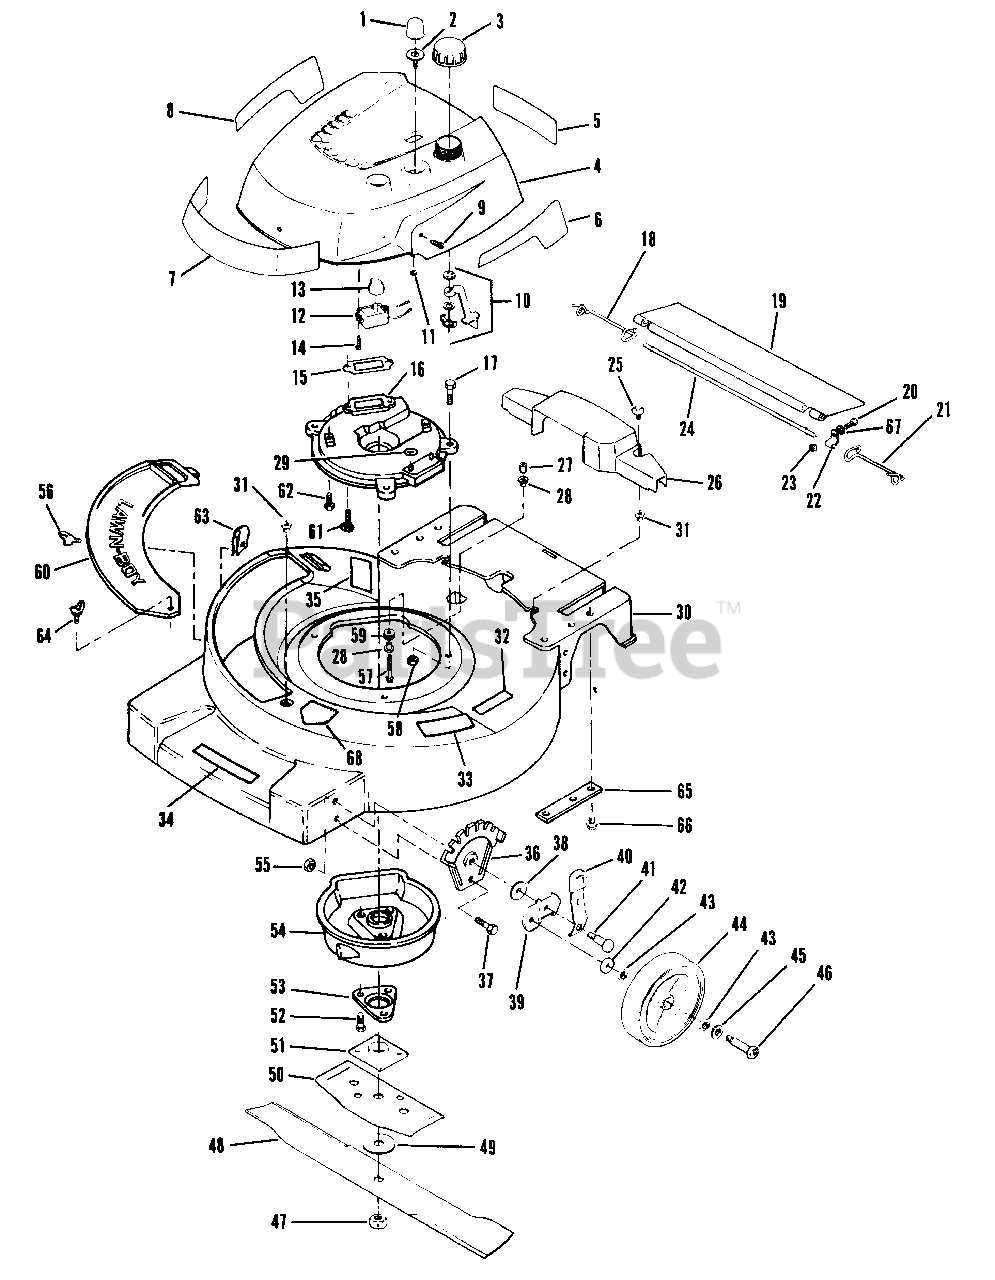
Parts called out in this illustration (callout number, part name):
1	Bulb-Primer
2	Base-Primer
3	Fuel Cap Assembly
4	Shroud-Engine
5	Decal-Instructions
6	Decal-L.H. 21"
7	Decal-Lawn-Boy
8	Decal-R.H. 21"
9	Screw-Shroud Mounting
10	Fuel Shut-Off Assembly
11	Nut-Primer Base Mounting
12	Switch-On-Off
13	Knob
14	Screw
15	Gasket-Exhaust
16	Plate-Muffler
17	Screw-Muffler Plate to Housing
18	Spring-R.H.
19	Shield-Trailing
20	Screw
21	Spring-L.H.
22	Clamp
23	Nut
24	Rod-Trailing Shield
25	Screw-Axle Cover Mounting
26	Cover-Drive Axle
27	Spacer
28	Spacer
29	Pushnut-Model Plate Mtg
30	Housing Assembly
31	Grommet
32	Decal-Starting Pad
33	Pad-Starting
34	Decal-Caution
35	Decal-Discharge Area
36	Plate-Height Adjust Backup
37	Screw-Height Adjust Plate
38	Washer
39	Bracket-Wheel Height Adjustment
40	Knob & Spring Assembly
41	Shoulder Bolt
42	Washer
43	Washer-Felt
44	Wheel-Front
45	Washer
46	Bolt-Wheel-Front
47	Nut-Blade
48	Blade-21"
49	Washer-Blade
50	Stiffener-Blade
51	Collar & Plate Assembly
52	Screw
53	Support-Crankshaft
54	Muffler Cover Assembly
55	Nut
56	Thumbscrew
57	Screw-Transmission to Housing
58	Nut-Muffler Plate to Housing
59	Grommet
60	Cover Plate
61	Screw-Muffler Plate to Block
62	Screw-Muffler Plate to Block
63	Speed Nut-Cover Plate Mounting
64	Wing Screw
65	Plate-Handle Bracket Support
66	Screw-Handle Bracket to Housing
67	Washer
68	Decal-Blade Contact Warning
